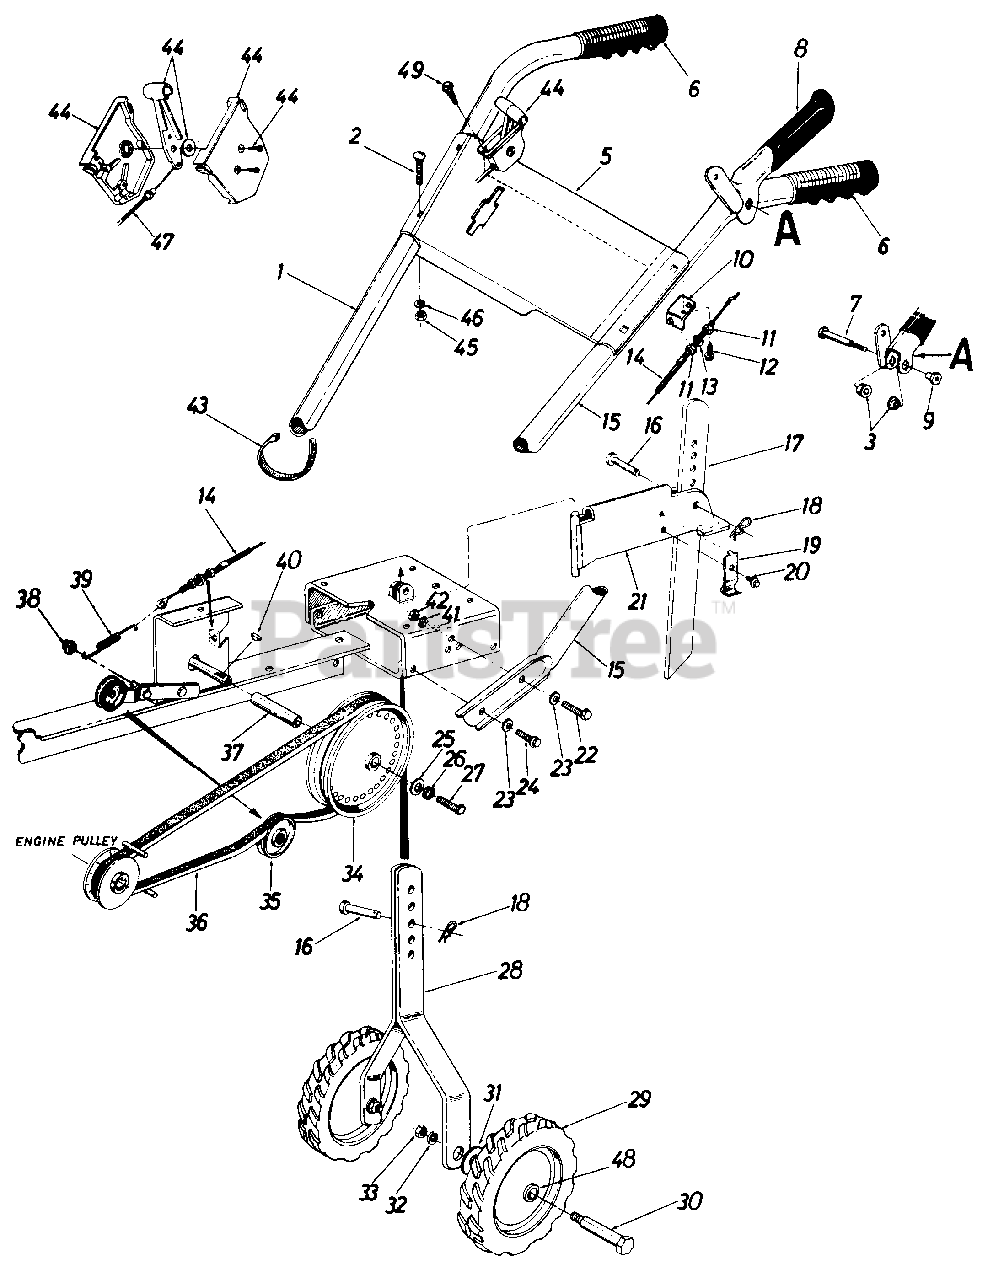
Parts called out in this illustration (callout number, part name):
1	Handle R.H.
2	Carriage Bolt 5/16-18 x 1.75" Lg.
3	Hex Flange Plastic Brg.
5	Handle Panel
6	Grip
7	Shld. Bolt .374" Dia. x 1.375" Lg.
8	Clutch Grip Ass'y.
9	Shld. Nut 1/4-20 Thd.
10	Cable Support Brkt.
11	Hex Jam Nut 5/16-24 Thd.
12	Hex Wash. Hd. Self-Tap Scr. 1/4-20 x .50" Lg.
13	L-Wash. 5/16" I.D.
14	Clutch Control Cable
15	Handle L.H.
16	Clevis Pin
17	Depth Bar
18	Hairpin Cotter
19	Depth Bar Spring
20	Hex Wash. Hd. Self-Tap Scr. 1/4-20 x .50" Lg.
21	Tailpiece Ass'y.
22	Hex Bolt 3/8-16 x 1.00" Lg.
23	Belleville Wash. 3/8" I.D.
24	Hex Wash. Hd. Self-Tap Scr. 3/8-24 x 7/8" Lg.
25	Fl-Wash. 25" I.D. x .930" O.D. x 120" Thk.
26	L-Wash. 1/4" I.D.
27	Hex Bolt 1/4-28 x .75" Lg.
28	Wheel Bracket Ass'y.
29	Wheel Ass'y. 10" x 1.75"
30	Shld. Bolt
31	Belleville Washer '/2" I.D.
32	L-Wash. 1/2" I.D.
33	Hex Nut 1/2-20 Thd.
34	Pulley 6" O.D.
35	Idler Pulley
36	V-Belt
37	Spacer
38	Cap Speed Nut
39	Extension Spring
40	Hi-Pro Key
41	L-Wash. 3/8" I.D.
42	Hex L-Nut 3/8-16 Thd.
43	Cable Ties
44	Throttle Control Box
45	Hex Nut 5/16-18 Thd.
46	L-Wash. 5/16" I.D.
47	Throttle Control Wire 35"
48	Bearing
49	Self-Tapping Scr. #10 x .50" Lg.
